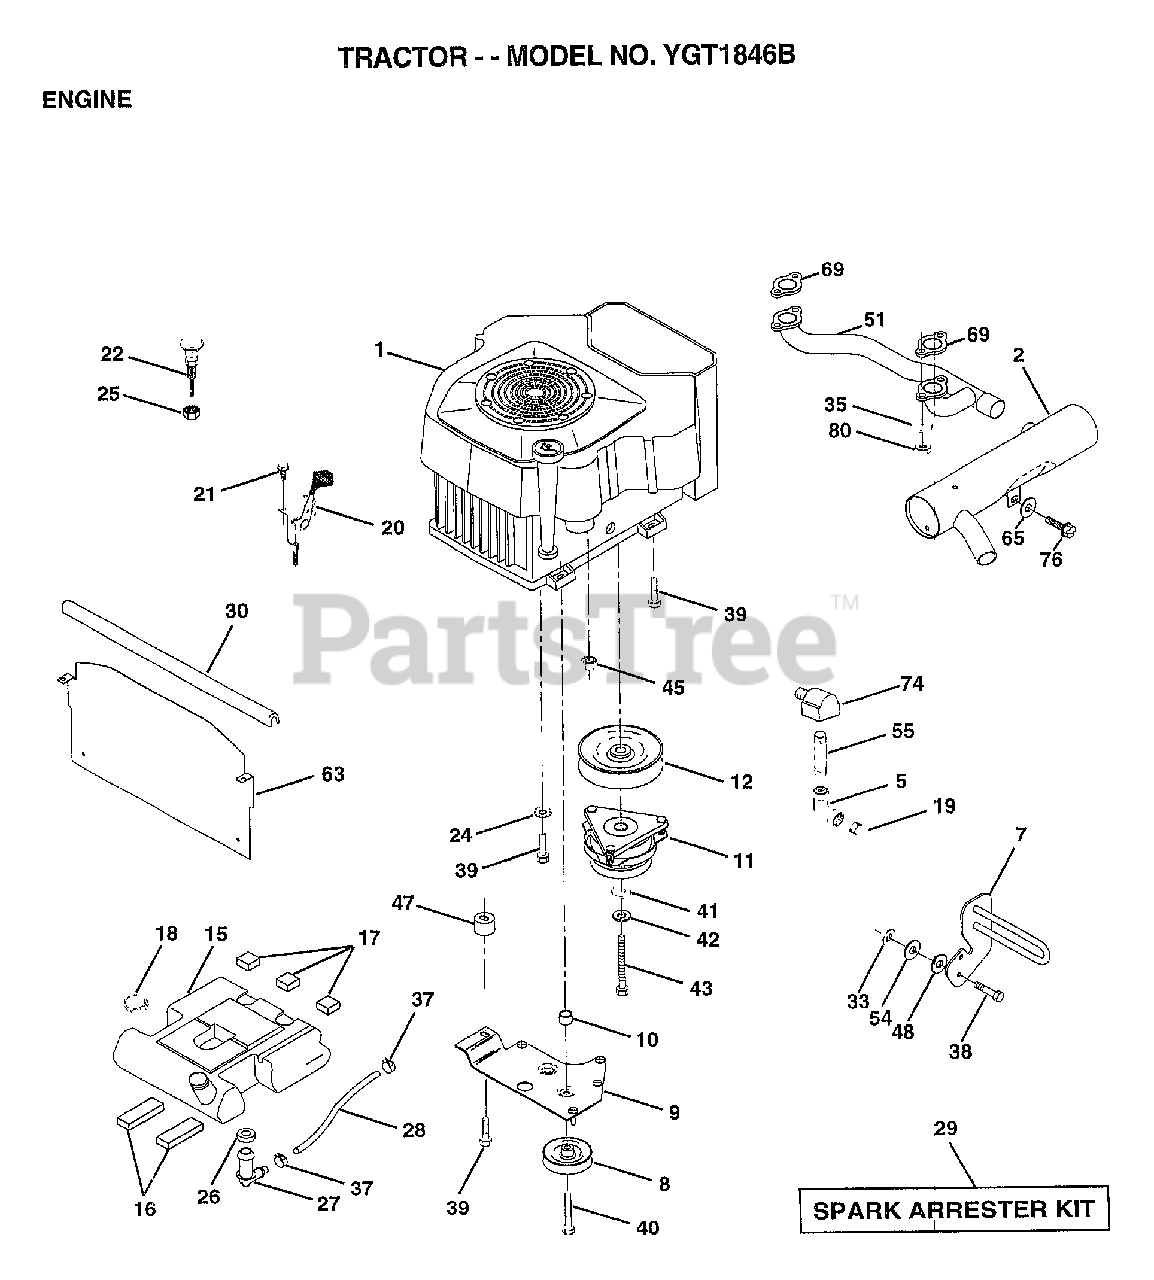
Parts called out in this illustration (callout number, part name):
2	MUFFLER.SIDE.VGT
5	ELBOW
7	GUARD.MUFFLER.ASM
9	KEEPER ASM BELT
10	BUSHING.
12	PULLEY.ENG.CLUTCH
15	TANK FUEL REAR
16	PAD IDLER TI
17	PAD-SPACER LT
18	CAP ASM FUEL
19	PLUG T
21	SCREW LT
22	CHOKE CONTROL
24	LOCKWASHER
25	"NUT,KEPS 3/8-24IM"
26	BUSHING OUTLET T
27	STEM.TANK.FUEL
29	SPARK ARREST KIT
30	EXTRUSION HOOD
33	NUT
35	WASHER.SPLIT
37	HOSE CLAMP
38	"BOLT,HEX"
39	SCREW.3/8-16X2.25
40	SCREW.TT.3/8-16X4
41	WASHER
42	LOCKWASHER
43	BOLT.7/16-20X4.25
45	NUT
47	SPACER.ENGINE
48	WASHER T
51	MANIFOLD.PIPE.VGT
54	WASHER
55	PIPE NIPPLE LT
63	HEAT.SHIELD.VGT.
65	WASHER
69	GASKET
74	ELBOW STREET BASS
76	SCREW
80	NUT FLANGE M8-125
